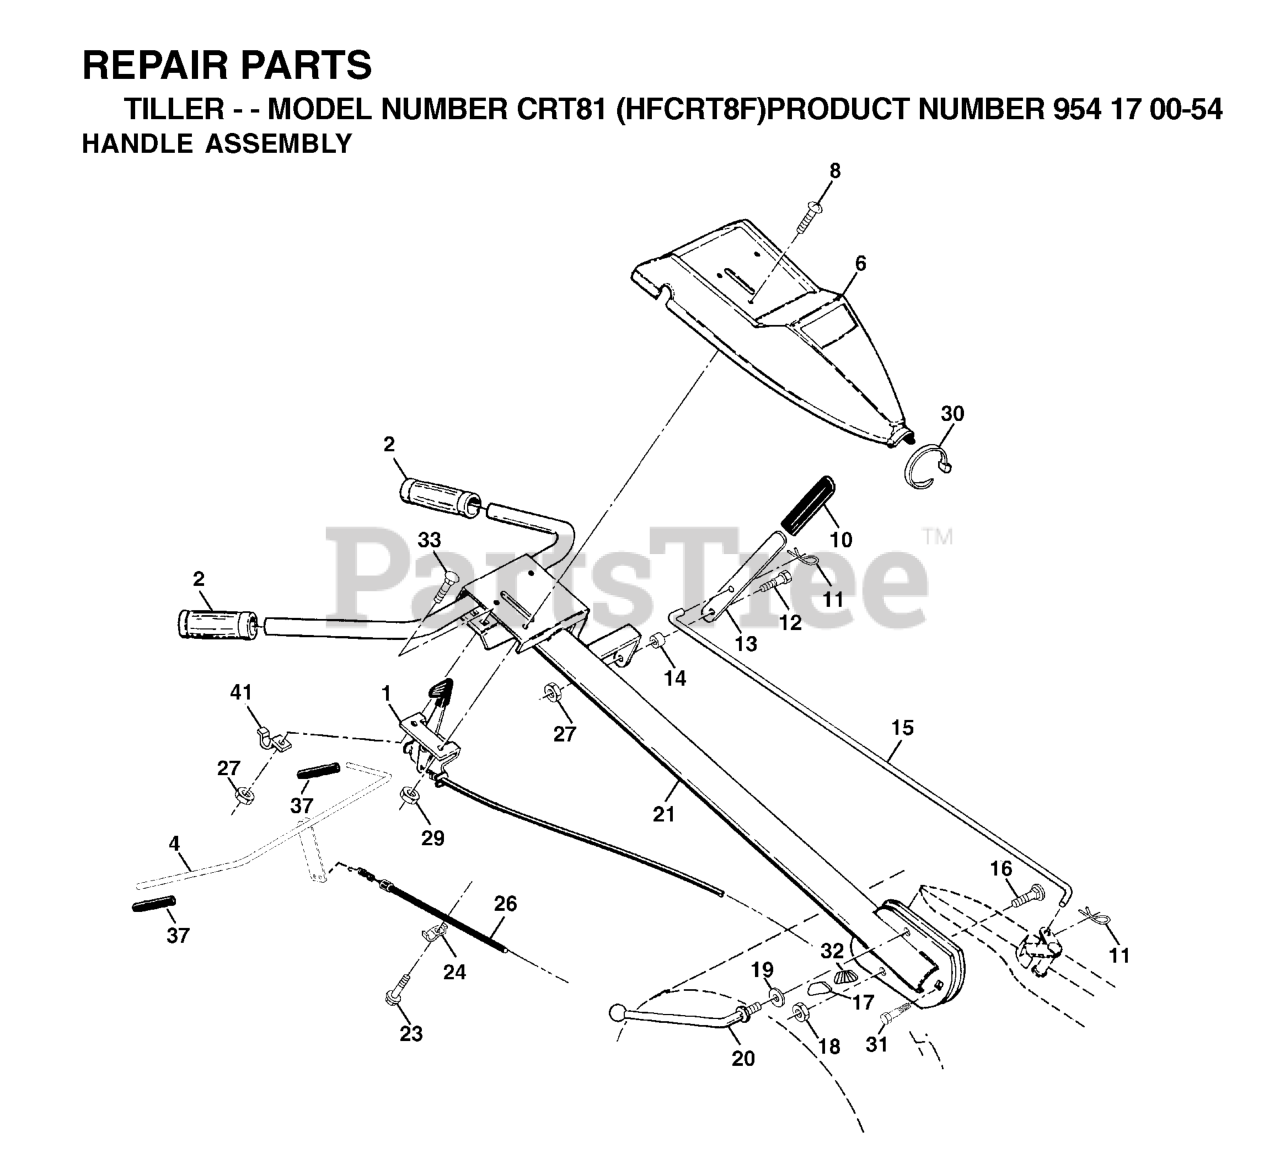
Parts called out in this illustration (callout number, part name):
1	THROTTLE.CONTROL.
2	KIT.GRIP.HANDLE.5.00.BLK.VINYL
4	CONTROL BAR ASSY
6	RP CONTROL PANEL
8	SCREW.PNHD.10-24
10	GRIP T
11	RETAINER M
12	SHOULDER BOLT ST
13	SHIFT HANDLE CRT
14	GROMMET.RUBBER.CRT.TILLER
15	SHIFT ROD CRT
16	BOLT D
17	LOCK.HANDLE.CRT
19	WASHER CRT
20	LEVER.LOCK.CRT
21	REPL BY 532 1805-17
23	TAPPING SCREW
24	CONDUIT.CLIP.PLATED
26	CABLE.CLUTCH
27	NUT T
29	NUT **
30	TIE CABLE CRT
31	BOLT.PIVOT
32	LOCK HANDLE
37	GRIP BAR CRT(1)
41	CLAMP.BAR.CRT.BLACK
